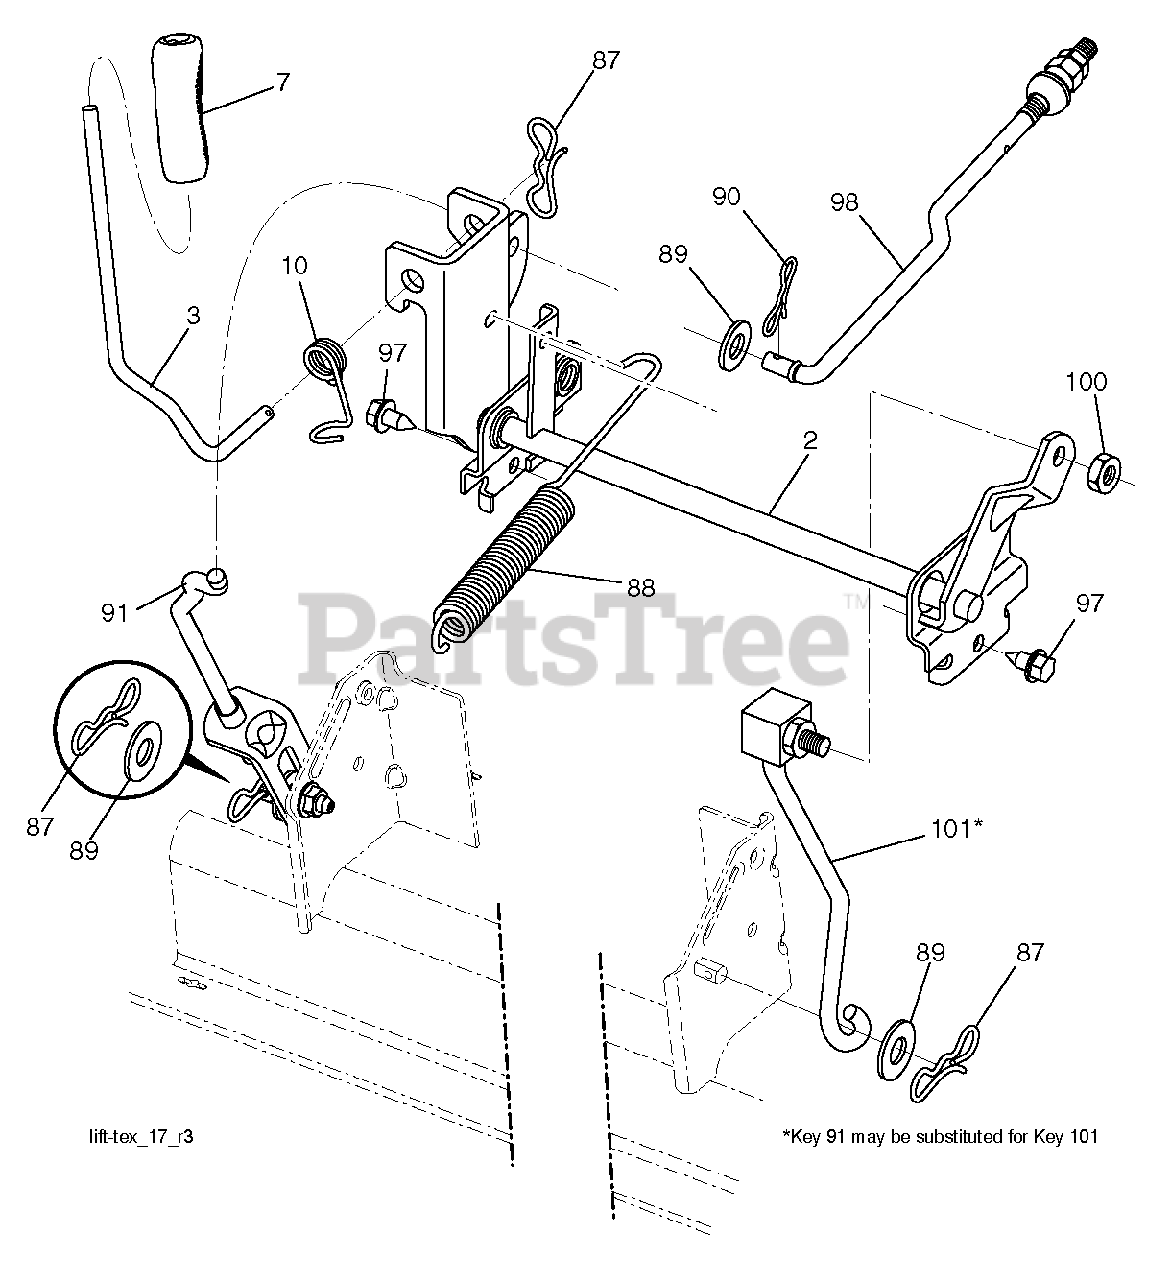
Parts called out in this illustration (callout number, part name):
2	SHAFT.ASM.CROSS.LIFT
3	LEVER.LIFT.HANDLE.LT
10	SPRING.TORSION.LIFT.HANDLE
87	PIN.COTTER.7/16.BOW TI
88	SPRING.LIFT.ASSIST
89	WASHER.CLEAR.ZINC
90	PIN.COTTER.5/16.BOW TI
91	LINK.LIFT.ASM.REAR.GT.
97	SCREW, 3/8-16X3/4
98	Front Link Assembly
100	LOCKNUT
